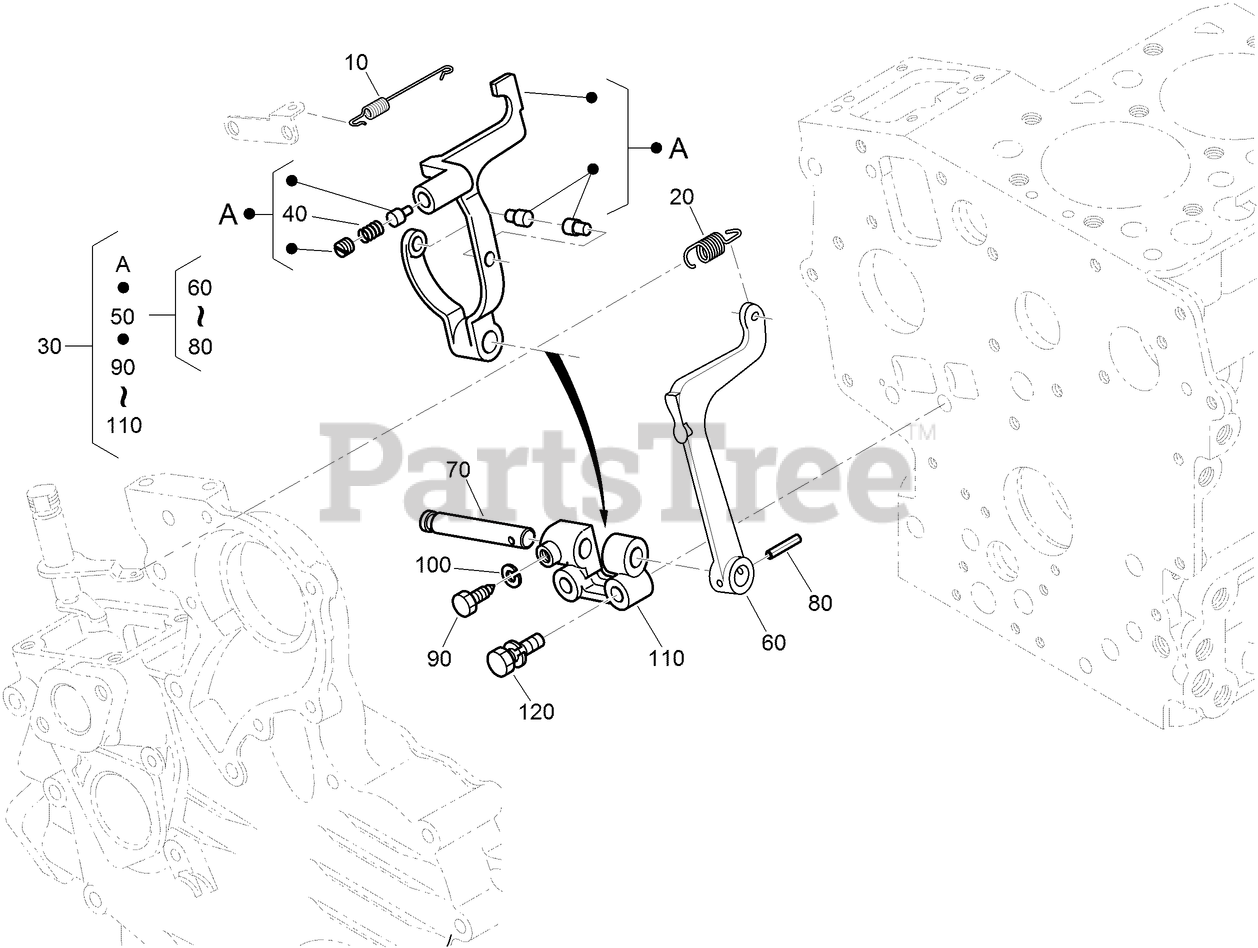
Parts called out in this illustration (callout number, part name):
10	SPRING-START
20	SPRING-GOVERNOR
30	FORK LEVER ASM
40	SPRING
50	FORK LEVER ASM
60	LEVER-FORK
70	SHAFT-LEVER, FORK
80	PIN-SPRING
100	WASHER-LOCK, SPRING
110	HOLDER-LEVER, FORK
